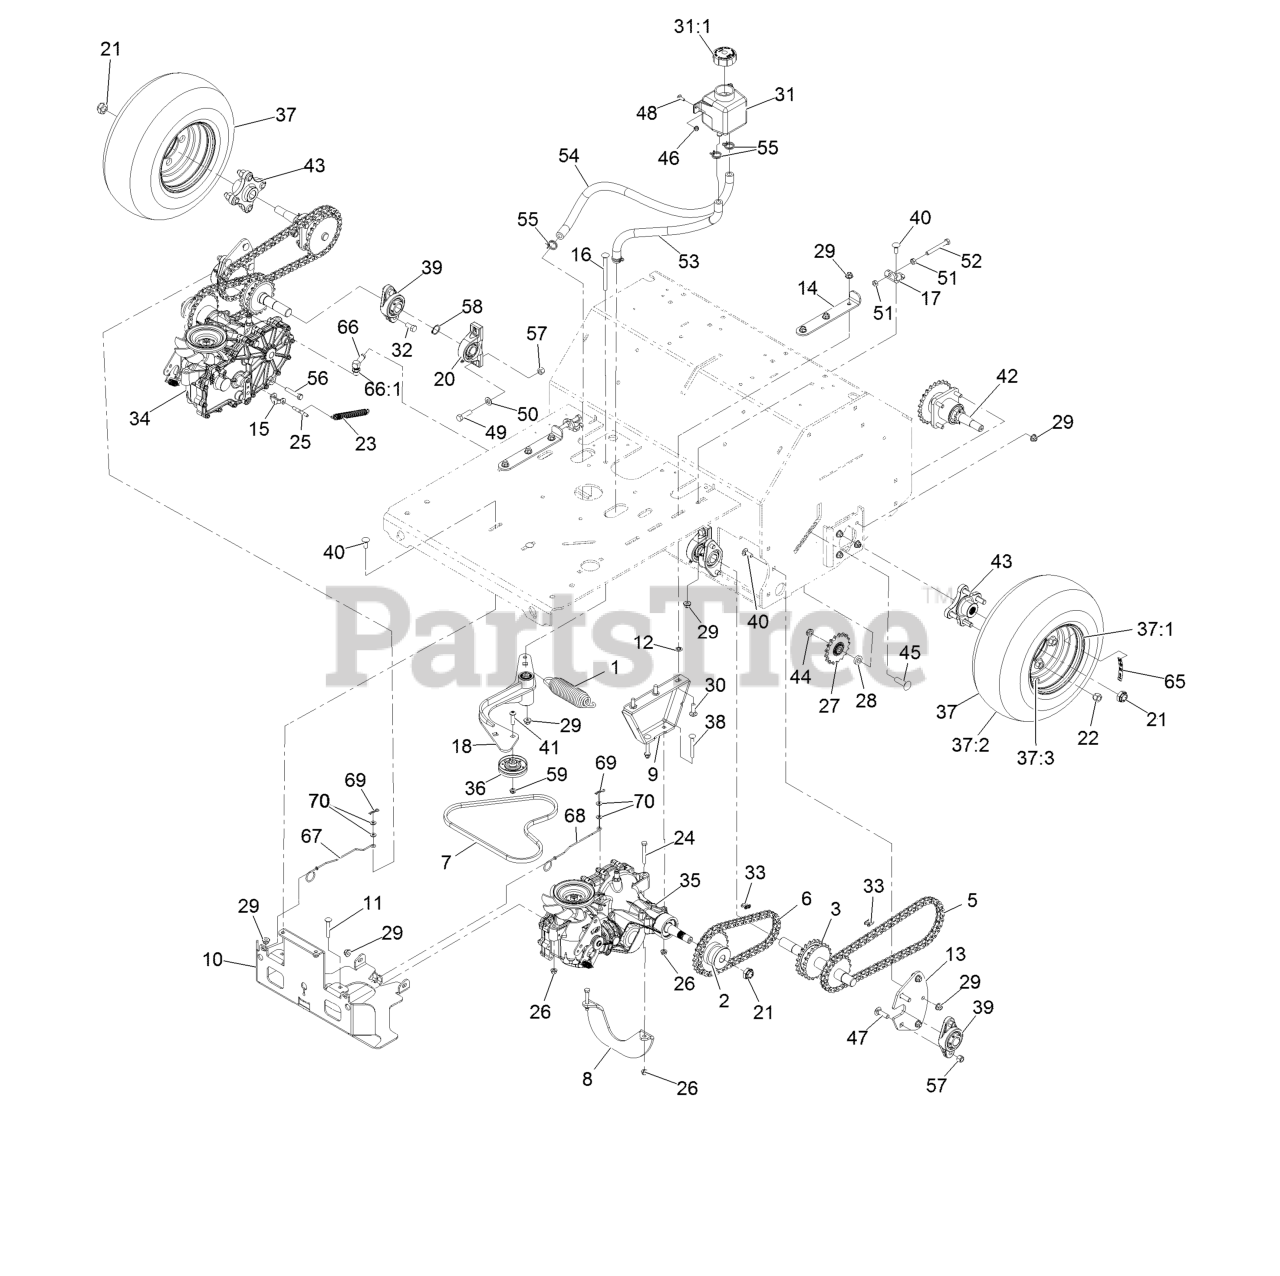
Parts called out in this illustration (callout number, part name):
1	Spring-Extension
2	Hub-Drive, Chain
3	Jackshaft
5	Chain-Roller
6	Chain-Roller
7	Belt-4L Section
8	Brace-Angle
9	Mount-Transmission
10	Guard-Transmission
11	Bolt-Carriage 5/16-18 X 2 1/4
12	Nut-Push 3/8-16
13	Plate-Jackshaft
14	Plate-Adjustment, Transmission
15	Yoke-Brake, Park
16	Bolt-CARR
17	Bracket-Hydro, Adjust
18	Idler Arm ASM
20	Bearing-Pillow Block
21	Nut-Lock
22	Nut-Lug 1/2-20
23	Spring-Door
24	Screw-HH 5/16-18 X 2 1/2
25	Pin-Brake, Park
26	Nut-Nyloc 5/16-18 Flg
27	Sprocket-Idler
29	Nut-Nyloc 3/8-16 Flg
30	Bolt-Carriage 3/8-16 X 1 1/4
31	Vent-Tank, HYD
31:1	Cap-Reservoir, HYD
32	Screw-HH
33	Link-Connecting
34	Transaxle-Zt3100, Rt (W/Pin)
35	Transaxle-Zt3100, Lt (W/Pin)
36	Pulley-Idler
37	Tire ASM (16 X 6.50-8)
37:1	Rim (8 X 5.375)
37:3	Stem-Valve
38	Bolt-Carriage 5/16-18 X 2 3/4
39	Bearing-Flange, 2 Bolt
40	Bolt-Carriage 3/8-16 X 1
41	Screw-HSBH
42	Axle And Bearing ASM
43	Hub-Offset
44	Nut-Nyloc 1/2-13 Thin
45	Screw-CARR
46	Nut-Nyloc 1/4-20 Flg
47	Bolt-Carriage 7/16-14 X 1 1/2
48	Bolt-Carriage 1/4-20 X 3/4
49	Screw-HH 7/16-14 X 1 1/2
50	Washer-7/16 SAE
51	Nut-Hex 3/8-16
52	Bolt-HH 3/8-16 X 3 Tap
53	Hose-Hydraulic
54	Hose-Hydraulic
55	Clamp-Hose
56	Screw-HH 3/8-16 X 2
57	Nut-Nyloc 7/16-14
58	Ring-Retaining
59	Nut-Nyloc 3/8-16 Thin
65	Decal-Hub, Wheel
66	Fitting-Elbow, 90
66:1	O-Ring
67	Rod-Bypass, RH
68	Rod-Bypass, LH
69	Hairpin-Cotter
99	Bottle-Oil, 32Oz Hydraulic
